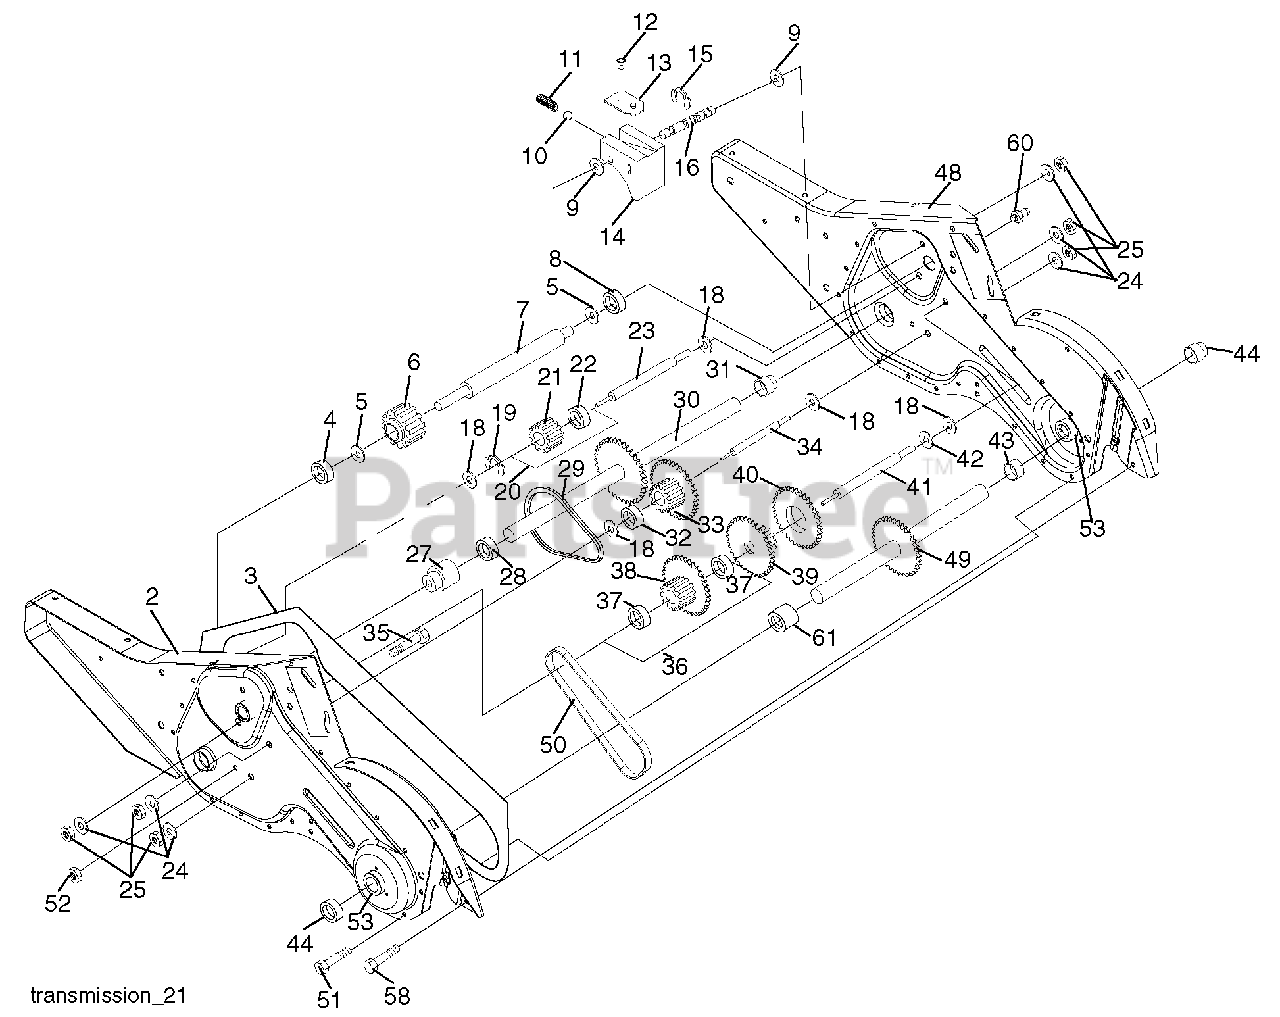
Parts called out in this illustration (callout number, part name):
1	Transmission Assembly
2	Gearcase, L.H. w/Bearing
3	Gasket, Gearcase
4	Bearing, Needle
5	Washer, Thrust 5/8 x 1.10 x 1/32
6	Pinion, Input
7	Shaft, Input
8	Bearing, Needle
9	Washer, Seal
10	Ball, Steel
11	Spring, Shift, Fork
12	O-Ring
13	Asm. Bracket Shift
14	Fork, Shift
15	Ring, Klip
16	Shaft, Shift
18	Washer
19	Ring, Klip
20	Gear, Assembly, Reverse Idler
21	Gear, Reverse Idler
22	Bearing, Needle
23	Shaft, Reverse Idler
24	Washer, Lock 7/16
25	Nut, Hex 7/16-20
27	Bearing, Shaft, Ground Drive L.H.
28	Spacer 0.765 x 1.125 x 1.23
29	Chain #35-50 Pitch
30	Ground Shaft Assembly
31	Bearing, Shaft, Ground Drive R.H.
32	Spacer 0.70 x 1.00 x 1.150
33	Sprocket and Gear Assembly
34	Shaft, Reduction (2nd)
35	Screw, Whiz, Lock 5/16-18 x 3-1/2
36	Sprocket Assembly w/Bearing
37	Bearing, Needle
38	Sprocket, Tine
39	Gear, Cluster, Red 1st & 2nd
40	Gear, Reverse
41	Shaft, Reduction (1st)
42	Washer, Thrust
43	Spacer 1.01 x 1.75 x 0.760
44	Seal Asm, Oil
48	Gearcase, R.H. w/Bearing
49	Shaft, Tine
50	Chain, Roller #50-50 Pitch
51	Screw 1/4-20 x 1/2
52	Nut, Hex 5/16-18
53	Kit, Bearing
58	Bolt Shoulder
60	Fitting Grease
61	Spacer 1.015 x 1.50 x .650
61	Grease, Plastilube #1
